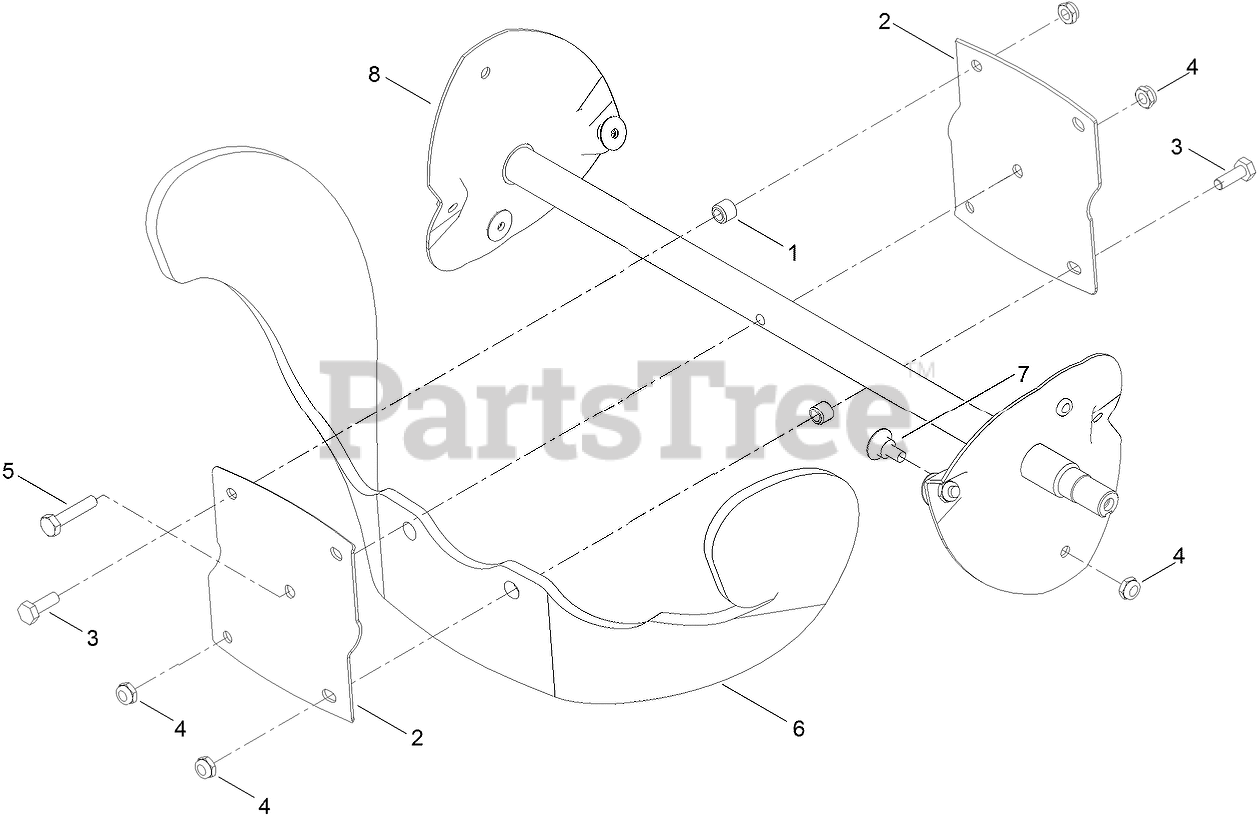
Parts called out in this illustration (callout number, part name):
1	SPACER-BLADE, ROTOR
2	HALF-ROTOR
3	SCREW-HH
4	NUT-HEX
5	SCREW-HH
6	BLADE-ROTOR
7	SCREW-COUNTERSUNK, OVAL
8	ROTOR KIT
